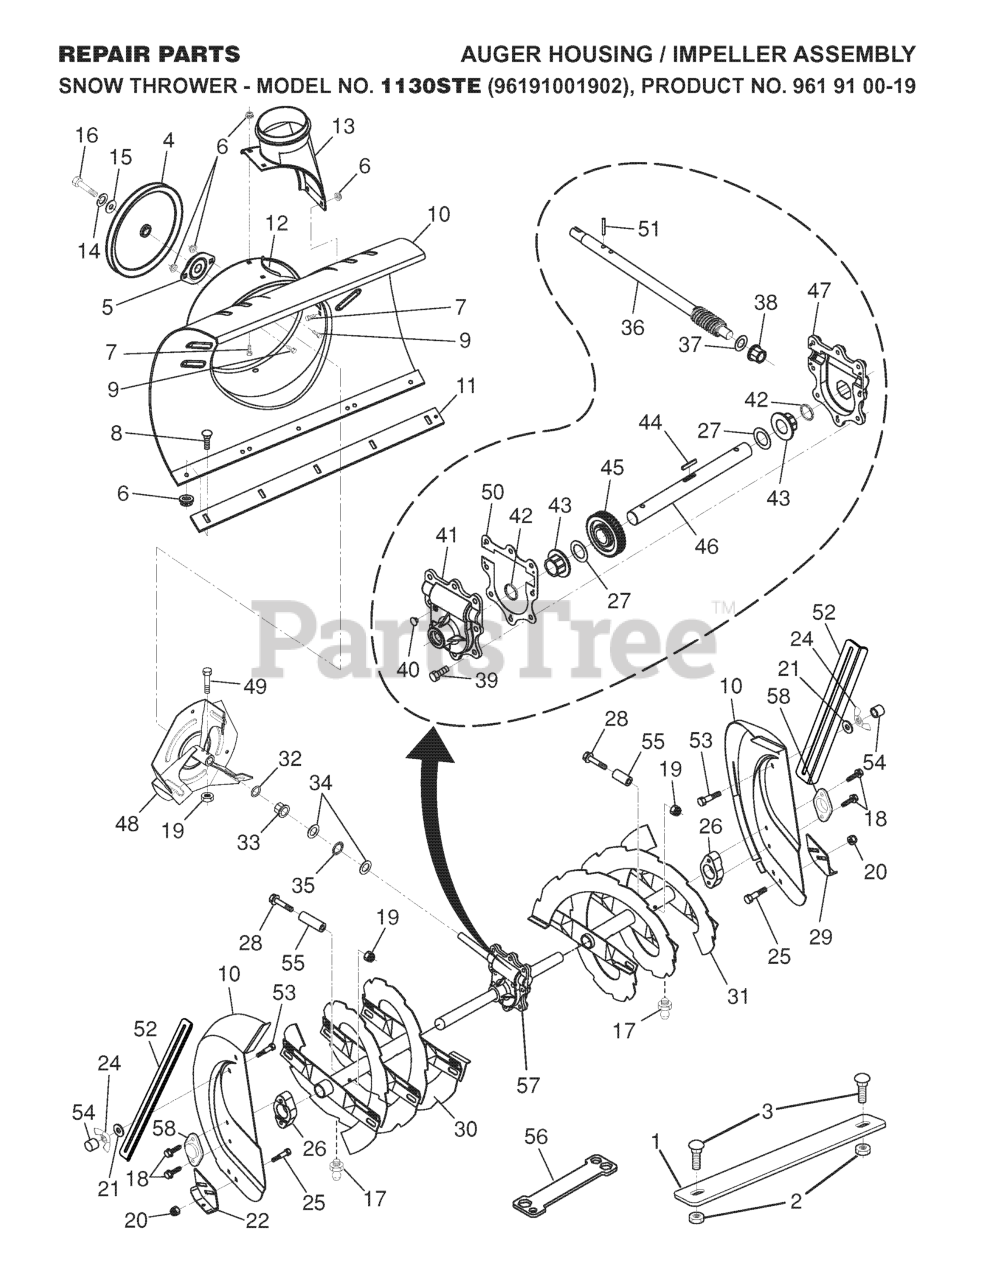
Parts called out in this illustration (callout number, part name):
1	WEIGHT AUGER HOUSING 30
2	NUT.LOCK.5/16-18
3	BOLT.CARRIAGE.5/16-18
4	PULLEY, IMPELLER
5	BEARING FLANGE
6	NUT.FLANGE.5/16
7	BOLT.CARRIAGE.5/16-18X
8	BOLT
9	BOLT, HEX HEAD 5/16-18
10	HOUSING, AUGER
11	BAR, SCRAPER
12	BRACKET, CORNER DISCHARGE
13	BASE DISCHARGE CHUTE
14	WASHER, FLAT
15	WASHER.LOCK.HVY.HLCL.SPR.5/16
16	CAPSCREW.HX.HD.5/16-18X1.00.NY
17	GREASE FITTING
18	SCREW, HEX HD 5/16X1
19	LOCKNUT.NYLOC.1/4-20
20	NUT.FLANGE.5/16
21	WASHER.12021.438X.75X.06.PLS
22	SKID PLATE RH
24	NUT WING PM
25	BOLT
26	BEARING RETAINER, PLASTIC
27	WASHER TRUST 1"
28	BOLT, SHEAR
29	SKID PLATE LH
30	AUGER ASSEMBLY, RH
31	AUGER ASSEMBLY, LH
33	BUSHING, FLANGE 3/4
34	WASHER, THRUST 3/4
35	BEARING TRUST 3/4 NTA-1220
36	SHAFT, IMPELLER
37	WASHER, THRUST 5/8
38	FLANGE BUSHING-5/8
39	HEX SCREW-5/16 X 3/4
40	CASE PLUG
41	GEARBOX HOUSING-RH
42	OIL SEAL
43	FLANGE BUSHING-1"
44	KEY, SQUARE 1/4 X .875
45	WORM GEAR
46	AUGER SHAFT
47	HOUSING.GEARBOX.LH(SERVICE)
48	IMPELLER ASSY
49	SCREW.HEX.HD1/4-20X
50	GEARBOX GASKET
51	PIN, ROLL 3/16 X 1-1/8
52	DRIFT CUTTER BAR
53	BOLT
54	STOP.11261.PLASTIC.30X50L.RED
55	SPACER.3943.SLEEVE.250X.47
56	RP WRENCH, SNOWTHROWER
57	GEARBOX.ASSEMBLY.AUGER
58	BEARING.BALL.AUGER.SHAFT
